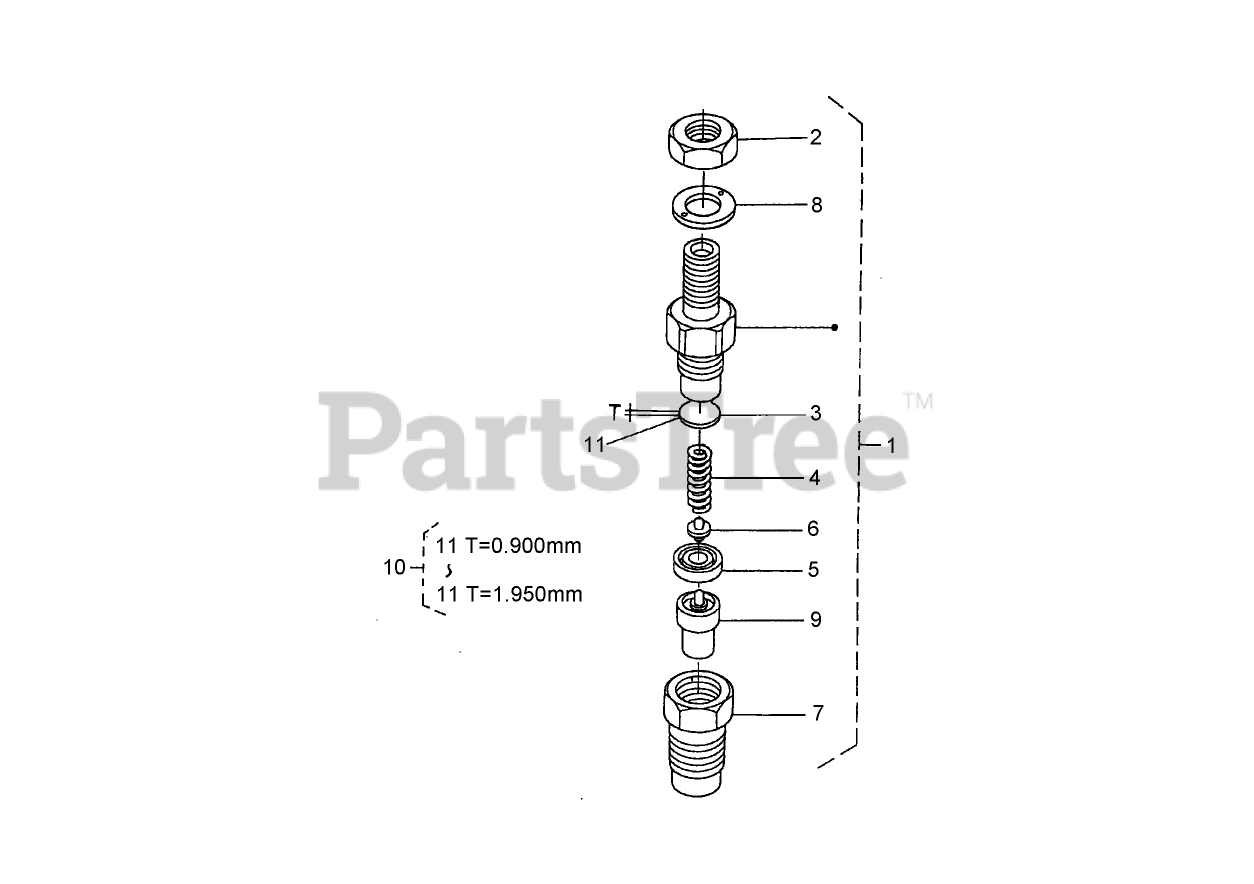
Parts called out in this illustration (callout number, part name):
1	NOZZLE HOLDER ASM
3	WASHER-ADJUSTING (0.900mm)
4	SPRING-NOZZLE
5	SPACER-DISTANCE
6	ROD-PUSH
7	NUT-NOZZLE
8	WASHER
9	PIECE-NOZZLE
10	ADJUSTING WASHER ASM
11	WASHER-ADJUSTING (0.900mm)
11	WASHER-ADJUSTING (0.925mm)
11	WASHER-ADJUSTING (0.950mm)
11	WASHER-ADJUSTING (0.975mm)
11	WASHER-ADJUSTING (1.000mm)
11	WASHER-ADJUSTING (1.025mm)
11	WASHER-ADJUSTING (1.050mm)
11	WASHER-ADJUSTING (1.075MM)
11	WASHER-ADJUSTING (1.100MM)
11	WASHER-ADJUSTING (1.125MM)
11	WASHER-ADJUSTING (1.150MM)
11	WASHER-ADJUSTING (1.175MM)
11	WASHER-ADJUSTING (1.200MM)
11	WASHER-ADJUSTING (1.225MM)
11	WASHER-ADJUSTING (1.250MM)
11	WASHER-ADJUSTING (1.275MM)
11	WASHER-ADJUSTING 1.300MM)
11	WASHER-ADJUSTING (1.325MM)
11	WASHER-ADJUSTING (1.350MM)
11	WASHER-ADJUSTING (1.375MM)
11	WASHER-ADJUSTING (1.400MM)
11	WASHER-ADJUSTING (1.425MM)
11	WASHER-ADJUSTING (1.450MM)
11	WASHER-ADJUSTING (1.475MM)
11	WASHER-ADJUSTING (1.500MM)
11	WASHER-ADJUSTING (1.525MM)
11	WASHER-ADJUSTING (1.550MM)
11	WASHER-ADJUSTING (1.575MM)
11	WASHER-ADJUSTING (1.600MM)
11	WASHER-ADJUSTING (1.625MM)
11	WASHER-ADJUSTING (1.650MM)
11	WASHER-ADJUSTING (1.675MM)
11	WASHER-ADJUSTING (1.700MM)
11	WASHER-ADJUSTING (1.725MM)
11	WASHER-ADJUSTING (1.750MM)
11	WASHER-ADJUSTING (1.775MM)
11	WASHER-ADJUSTING (1.800MM)
11	WASHER-ADJUSTING (1.825MM)
11	WASHER-ADJUSTING (1.850MM)
11	WASHER-ADJUSTING (1.875MM)
11	WASHER-ADJUSTING (1.900MM)
11	WASHER-ADJUSTING (1.925MM)
11	WASHER-ADJUSTING (1.950MM)
